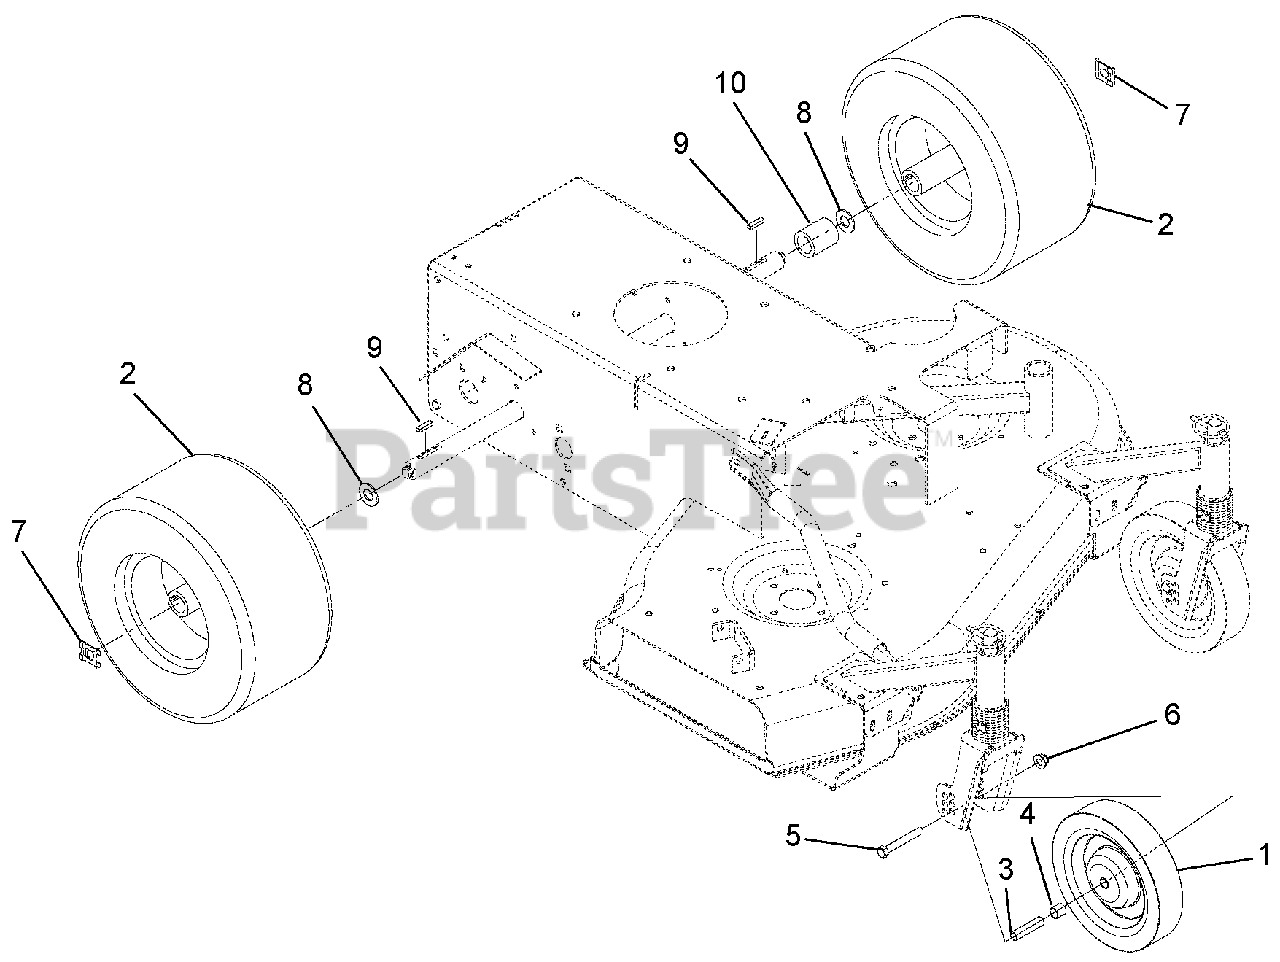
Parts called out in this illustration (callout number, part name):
1	WHEEL, 8.0X1.75X.50 - BALL BRG
2	ASSY, TIRE/WHEEL 6X13
3	SPCR, WHEEL .385X.500X2.00
4	SPACER-WHEEL
5	@BLT-HEX .38-16X2.75 GR5 YWZC
6	@NUT-LK-NYL-FLG .38-16 YWZC
7	CLIP, SNAP .625 DIA
8	@WSHR-FL-STL.656X1.31X.095 YWZ
9	KEY-RECT .25X.188X1.00
10	SPACER, 1.0X1.5X1.57
